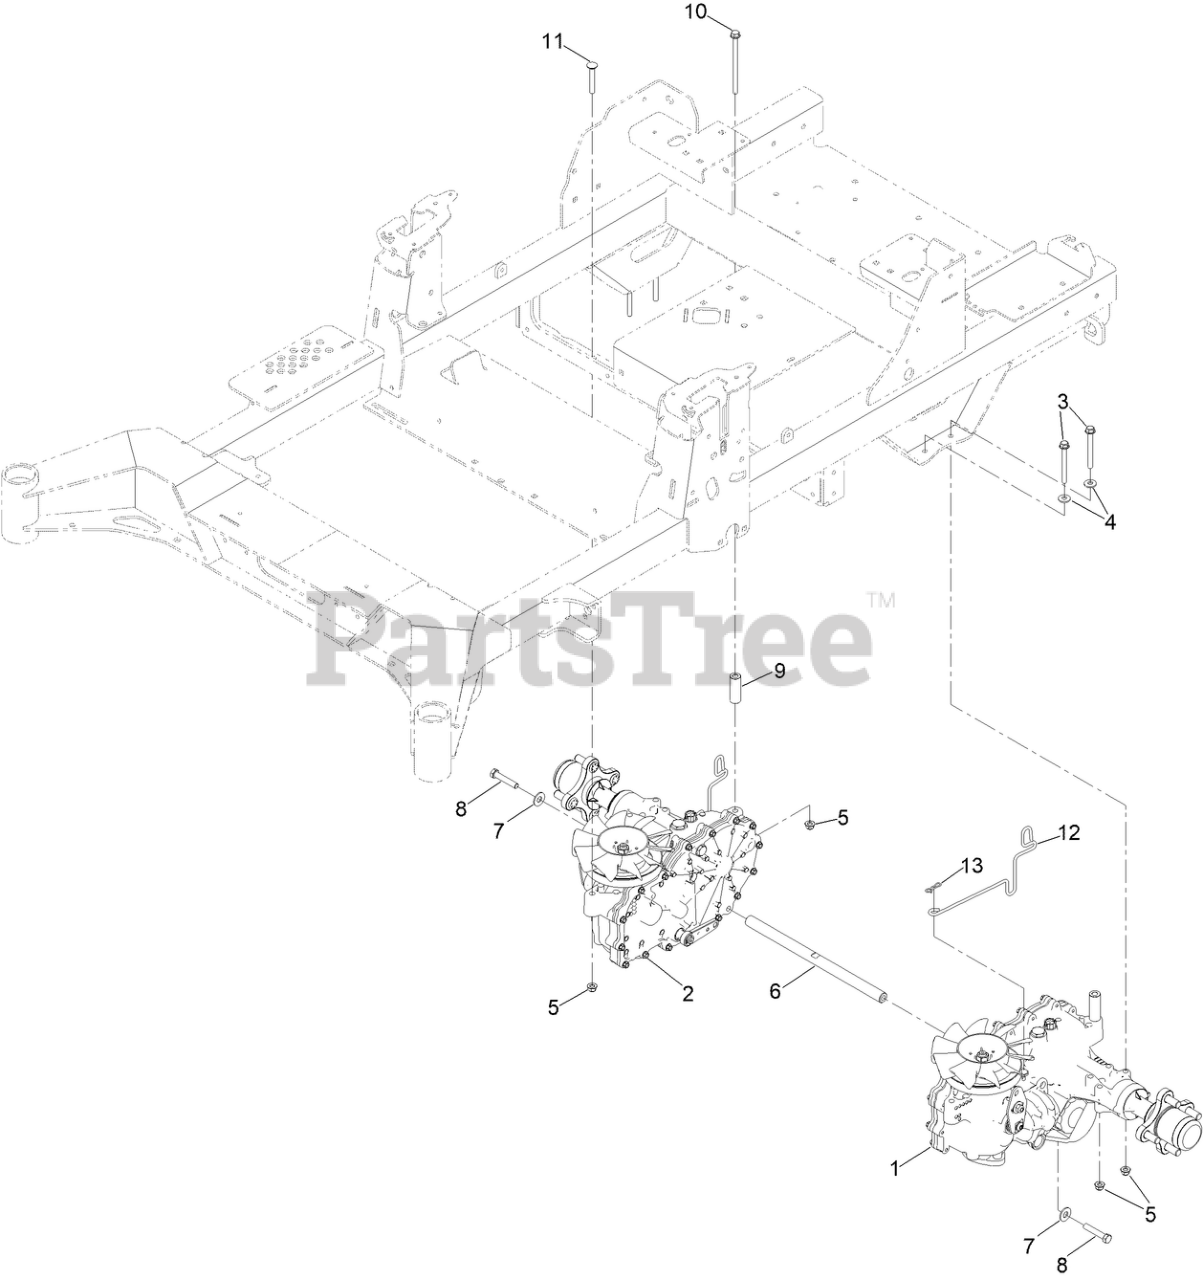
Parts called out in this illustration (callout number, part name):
1	TRANSAXLE ASM
2	TRANSAXLE ASM
3	SCREW-HHF
4	WASHER-SPRING
5	NUT-HF, NI
6	SHAFT-SPACER
7	WASHER-FLAT
8	SCREW-HH W/LOCTITE
9	SPACER-HYDRO
10	SCREW HHF
11	BOLT-CARR
12	ROD-BYPASS
13	PIN-COTTER, LOCKING
